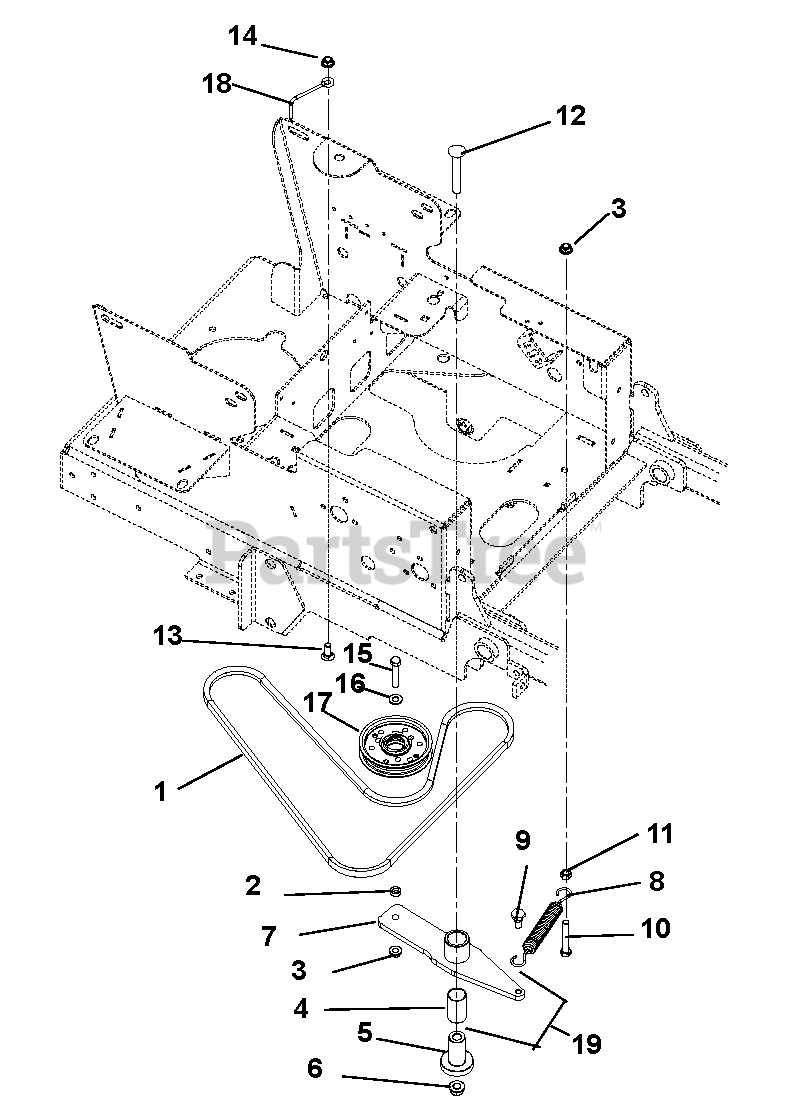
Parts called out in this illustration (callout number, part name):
1	V-BELT, 4L-WRAPPED
2	BSHG-SLV .377X.624X.235
3	@NUT-LK-NYL-FLG .38-16 YWZC
4	BSHG, 1.00 X 1.125 X 1.937
5	BEARING, PEDESTAL
6	@NUT-LK-NYL-FLG .50-13 YWZC
7	WMT, HYDRO DRIVE IDLER ARM
8	SPRING, EXTENSION
9	BLT,SHLDR EP .38-16X.30 HEX YZ
10	@BLT-HEX .38-16X2.50 GR5 YWZC
11	@NUT-HEX .38-16 YWZC
12	@BLT-RHDSSQNK .50-13X3.50 G5YZ
13	@BLT-RDHDSQNK .38-16X1.00 G5YZ
14	@NUT-LK-NYL-FLG .38-16 YWZC
15	@BLT-HEX .38-16X2.00 GR5 YWZC
16	@WSHR-FL-STL.406X.812X.065 YWZ
17	ASM, 4" IDLER (.75 WIDE)
18	BELT FINGER
19	ASSY, GROUND DRIVE IDLER
